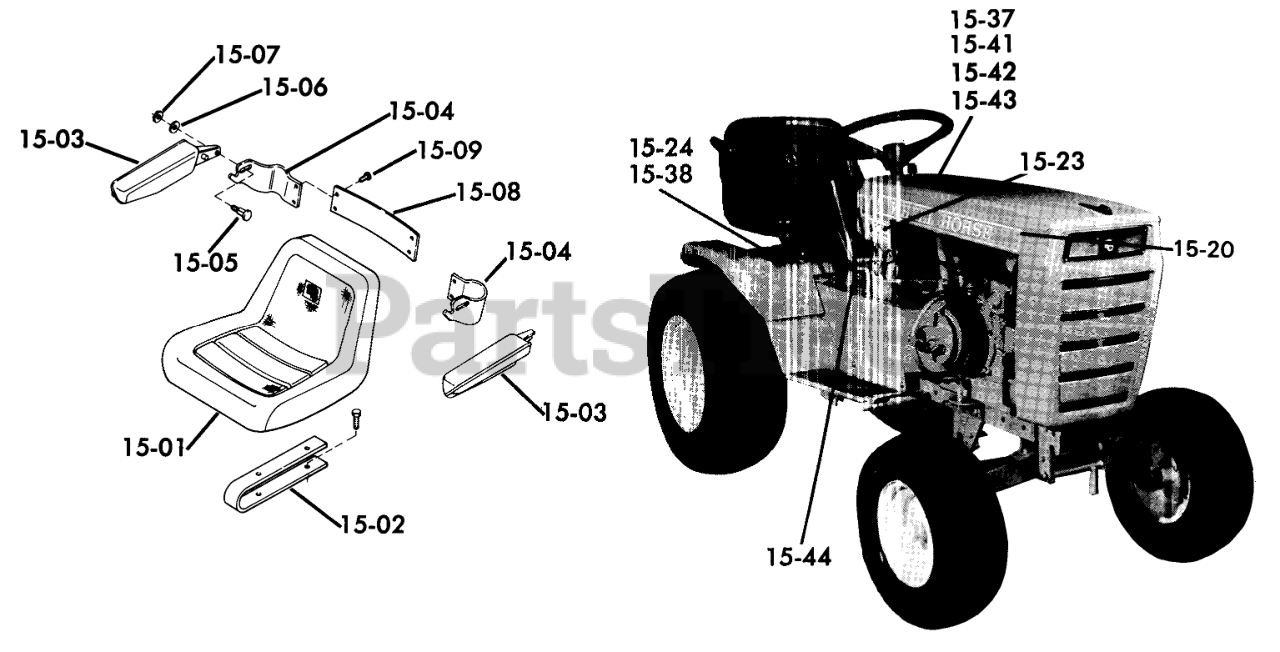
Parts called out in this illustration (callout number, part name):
15-01	Seat
15-02	Seat Spring
15-03	Arm R.H.
15-03	Arm L.H.
15-04	Bracket R.H.
15-04	Bracket L.H.
15-05	Bolt (Slide Pivot)
15-06	Washer, Bellville
15-07	Nut (Pivot)
15-08	Bracket-Arm Brace
15-09	Screw
15-20	Decal
15-23	Decal
15-23	DECAL C 160
15-24	DECAL-WHEEL HORSE
15-37	Lockwasher
15-38	Decal-Maintenance
15-41	DECAL PTO SPD. CONT
15-42	DECAL-HAND LIFT
15-43	Decal-Caution
15-44	Decal-Parking Brake
15-44	Decal
